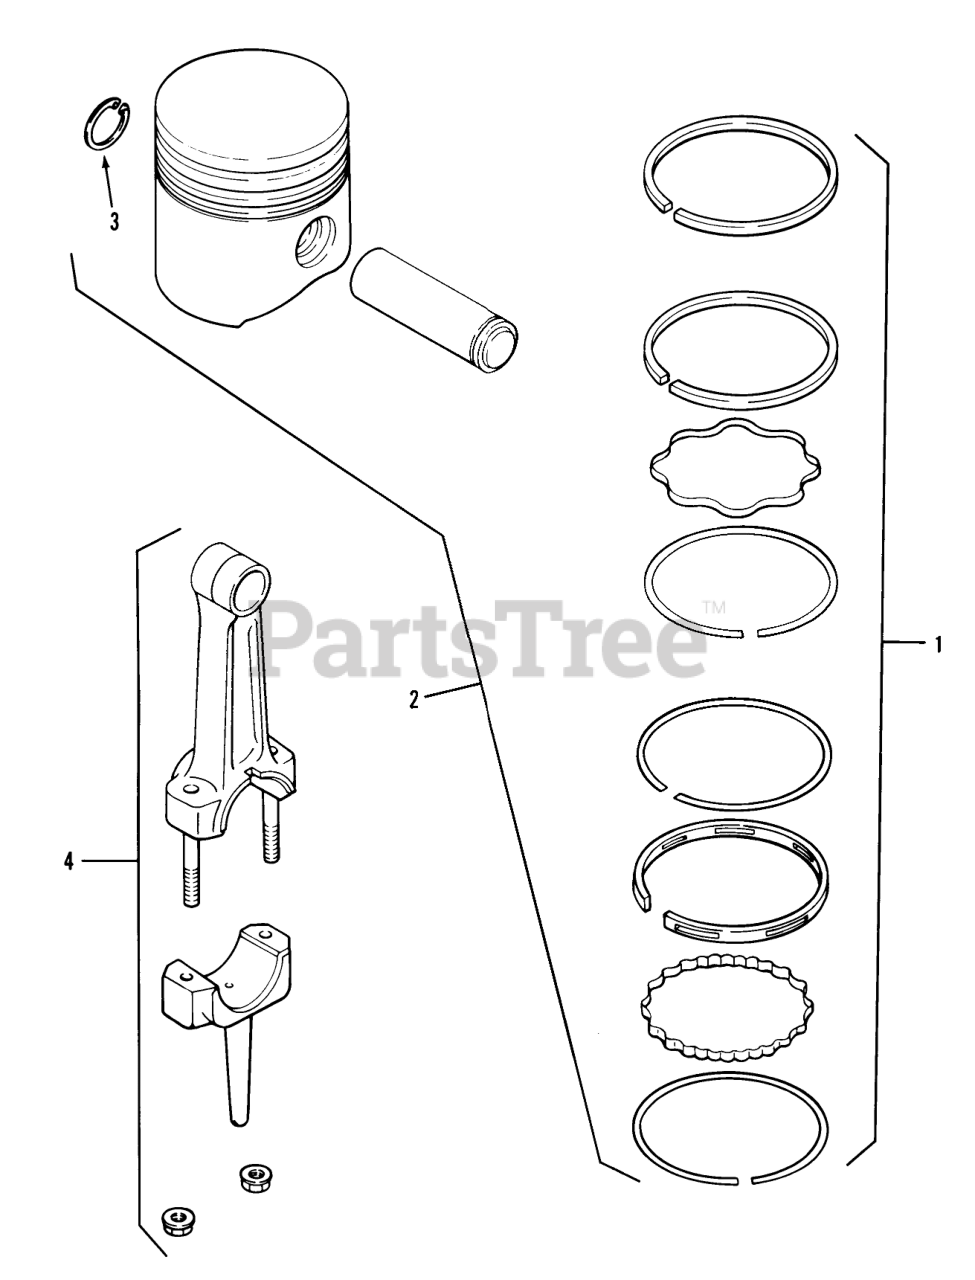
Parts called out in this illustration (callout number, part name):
1	Ring Set Std. 308 Only (before serial #1601300012)
2	Piston w/ Ring Set Std. & .003 308 (before serial #1601300012)
2	Piston w/ Ring Set .030 308 (after serial #1601300002)
3	Piston Pin Retainer 308 Only
4	Connecting Rod Std. 308 Only (before serial #1601300012)
